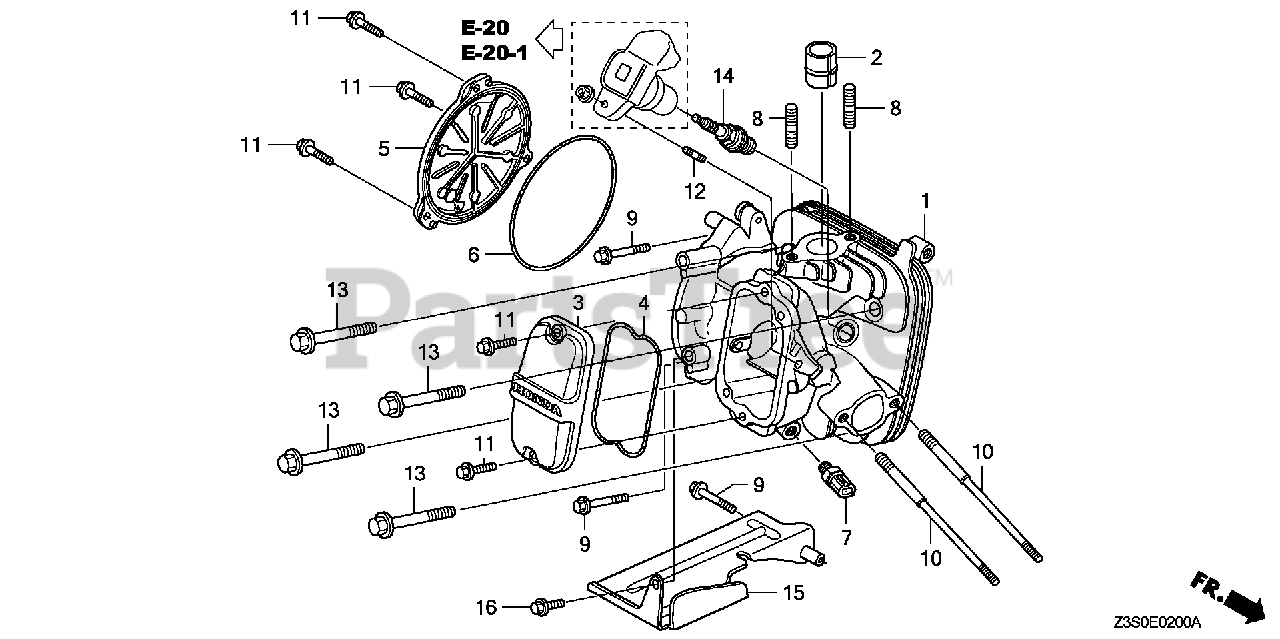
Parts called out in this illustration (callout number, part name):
1	CYLINDER HEAD
2	LINER, PORT
3	COVER, CYLINDER HEAD
4	GASKET, HEAD COVER
5	COVER, CYLINDER HEAD SIDE
6	GASKET, SIDE COVER
7	SENSOR ASSY., TEMPERATURE
8	BOLT 2, STUD (8X32)
9	BOLT, FLANGE (6X32)
10	BOLT, STUD (8X115)
11	BOLT, FLANGE (6X25) Use up to Engine SN 2056819.
12	BOLT 2, STUD (6X20)
13	BOLT, FLANGE (10X70)
14	SPARK PLUG (K16PR-UR)
14	SPARK PLUG (BKR5E-E)
14	SPARK PLUG (K20PR-UR)
14	SPARK PLUG (BKR6E-E)
14	SPARK PLUG (K22PR-UR)
14	SPARK PLUG (BKR7E-E)
